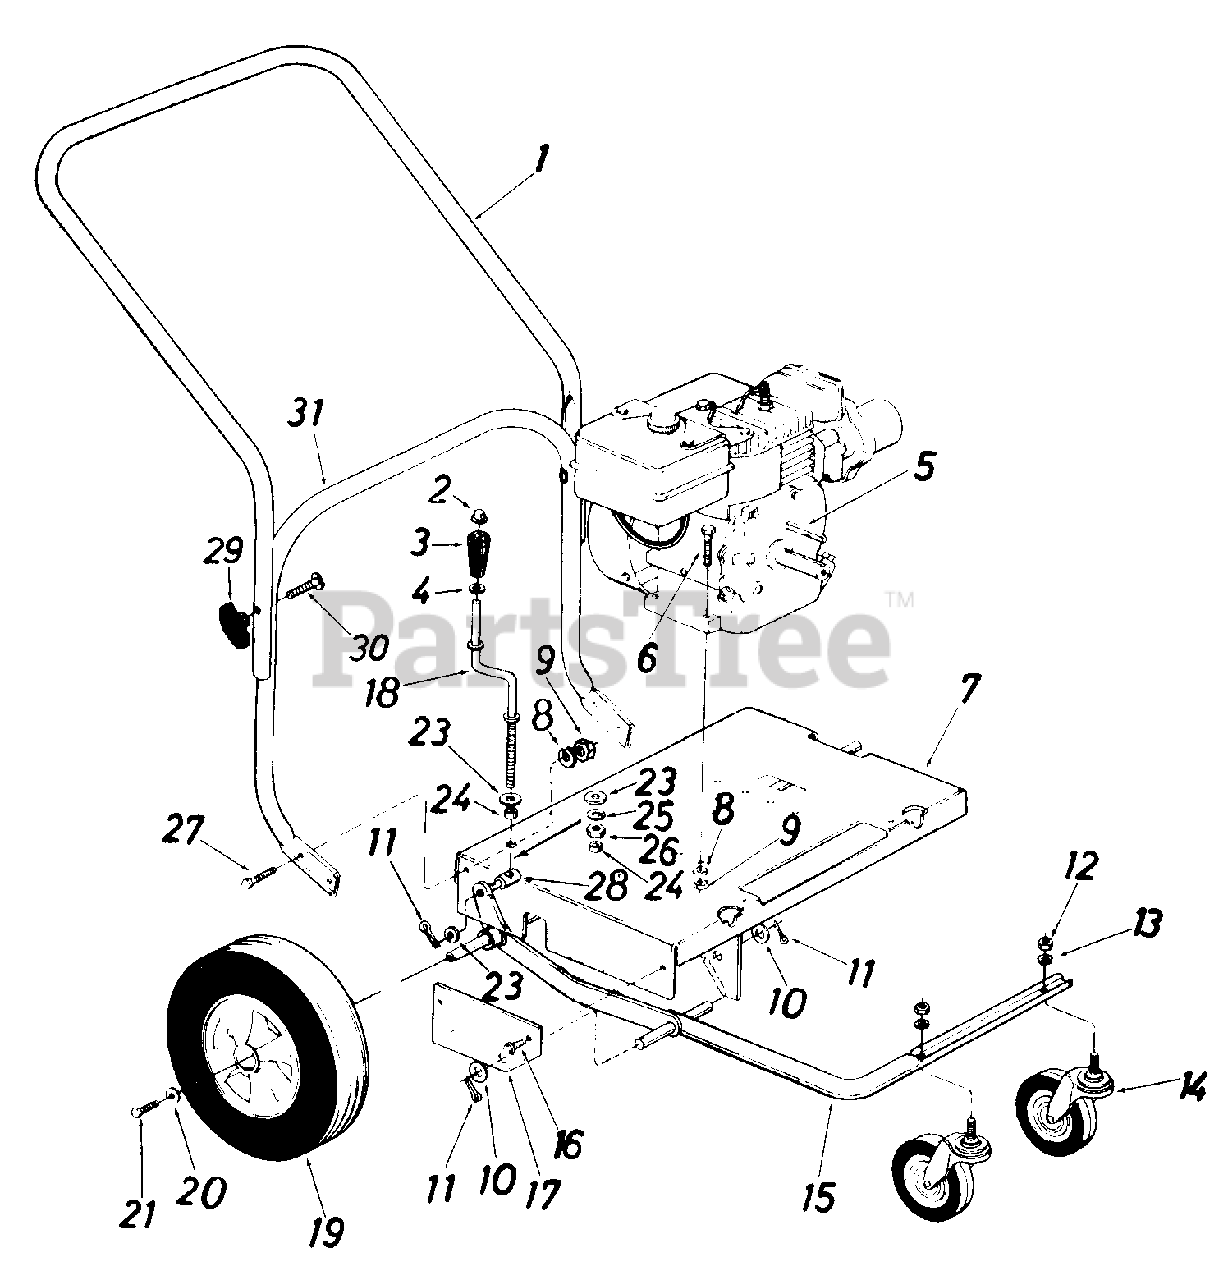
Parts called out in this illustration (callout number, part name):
2	Push Nut 3/8" Rod
3	Crank Knob
4	Fl.-Wash .385" I.D. x .62" O D.
5	Sq. Key 1/4" x 2.0" Lg.
6	Hex Bolt 5/16-18 x 1.50" Lg.
9	Hex Nut 5/16-18 Thd
10	Fl.-Wash. .63" I.D. x i.25" 0. D.
11	Cotter Pin 1/8" Dia. x 1.0" Lg.
12	Hex Nut 1/2-13 Thd.
13	L.-Wash. 1 /2 " 1 . D.
14	Swivel CasterWheel 5" Dia. x 1.25"
19	Wheel Ass'y. Comp. 10.5" x 4" (Steel)
20	Fl.-Wash. 34" I.D. x .87" 0. D.
21	Hex Locking Bolt5/16-24 x.62" Lg.
23	F l . -Wash . .38 " I . D . x .57 " O . D.
24	Spacer .382" I.D. x .50" O.D. x .180" Lg.
25	L.-Wash. 3/8" I.D.
26	Hex Nut 3/8-8 Thd.
27	Hex Bolt 5/16-18 x .75" Lg.
28	Ferrule
29	Hand Knob
30	Carriage BoIt 5/16-18 x 2.0" Lg.
